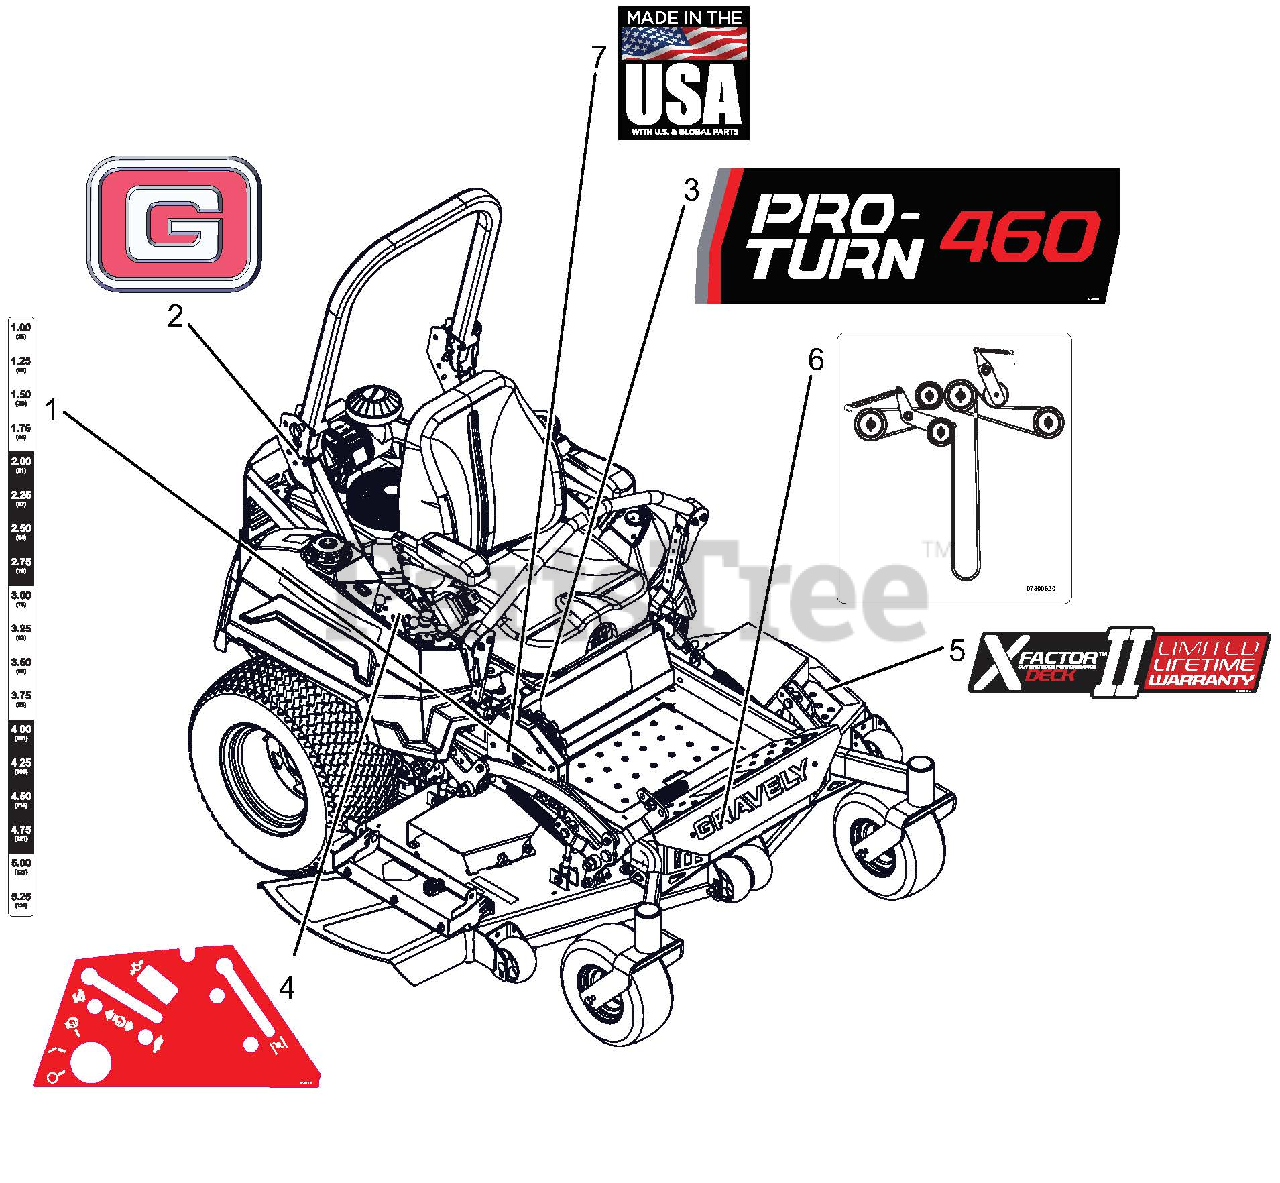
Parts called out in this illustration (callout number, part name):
1	DECAL, PT400 HEIGHT OF CUT
2	DECAL, GRAVELY BRAND
3	DECAL, PRO-TURN 460
4	DECAL, NON-EFI CONTROL PANEL
5	DECAL, X-FACTOR DECK
6	DCL,BELT ROUTE-RH BK-SIDE IDLR
7	DECAL, MADE IN USA
